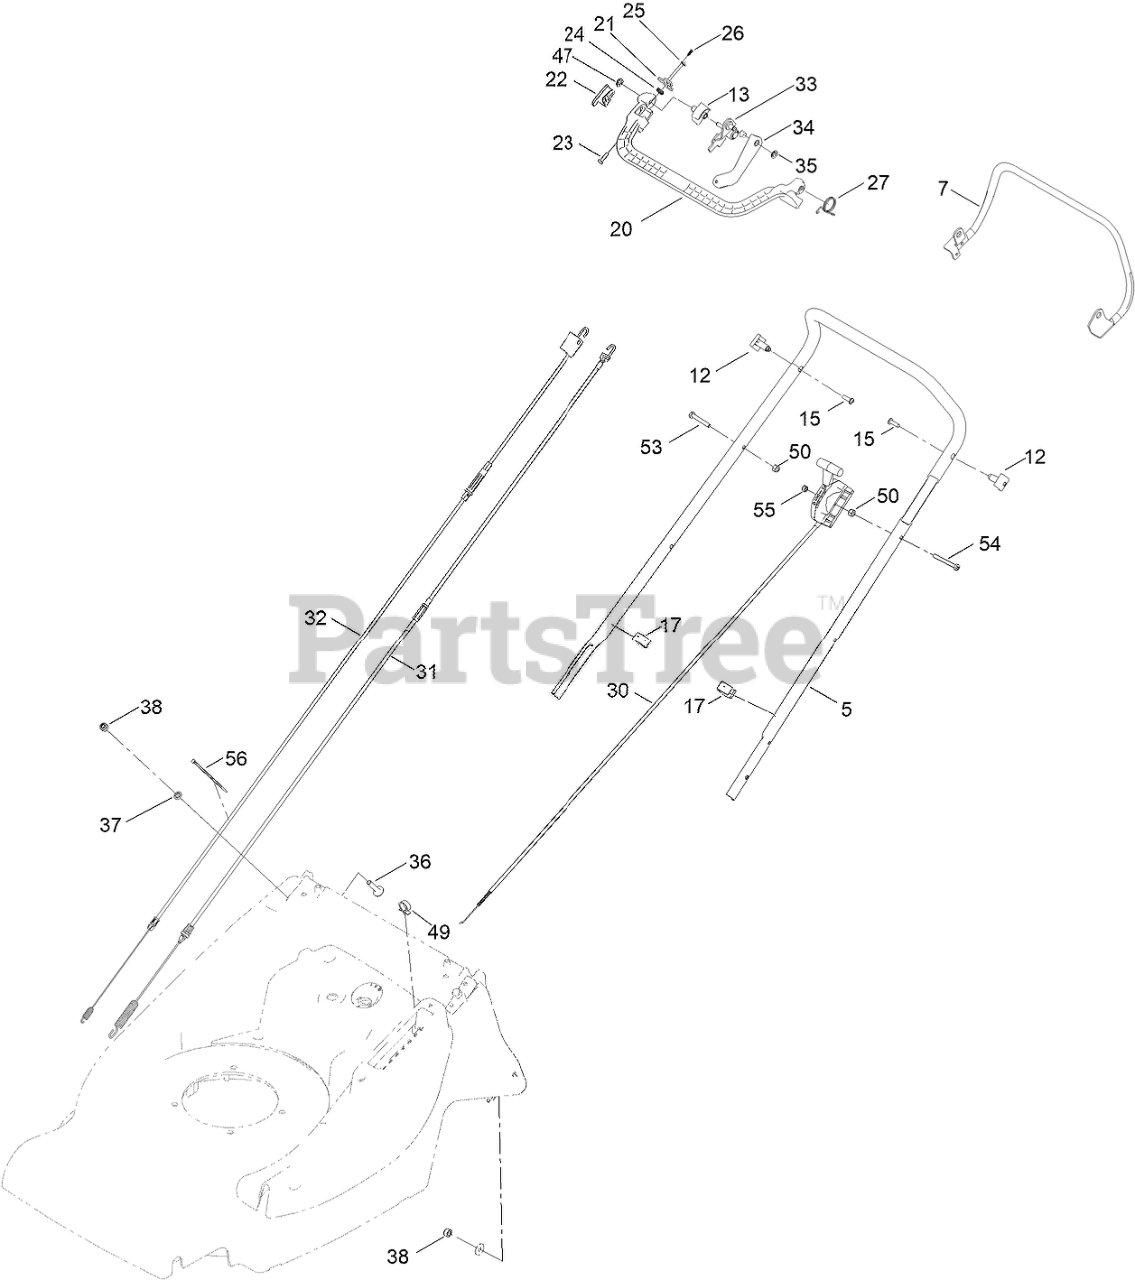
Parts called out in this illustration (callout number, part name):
5	HANDLEBAR-UPPER
7	LEVER-CLUTCH, GEARBOX
12	PIN-PIVOT
13	CLAMP-BAR
15	SCREW
17	GUIDE-CABLE
20	ARM-BAIL
21	LEVER-CATCH
22	LATCH-BUTTON
23	LATCH-PIN
24	LEVER-BAIL, SPRING
25	FASTENER-STARLOCK, PUSH-ON
26	CLIP-TREE
27	LEVER-BAIL ARM, SPRING
30	THROTTLE-CONTROL
32	CLUTCH-CABLE, 3 SPEED
33	ANCHOR PLATE WELDED
34	BBC LINKAGE ASSEMBLY
35	WASHER-STARLOCK
36	BOLT-COACH
37	GRIP-FIX
38	NUT-HEX, NI
47	STARLOCK-DOMED
49	CLIP-CONDUIT, TWIN
50	NUT-HEX
53	BOLT
54	SETSCREW
55	NUT-NYLOC
56	TIE-CABLE
